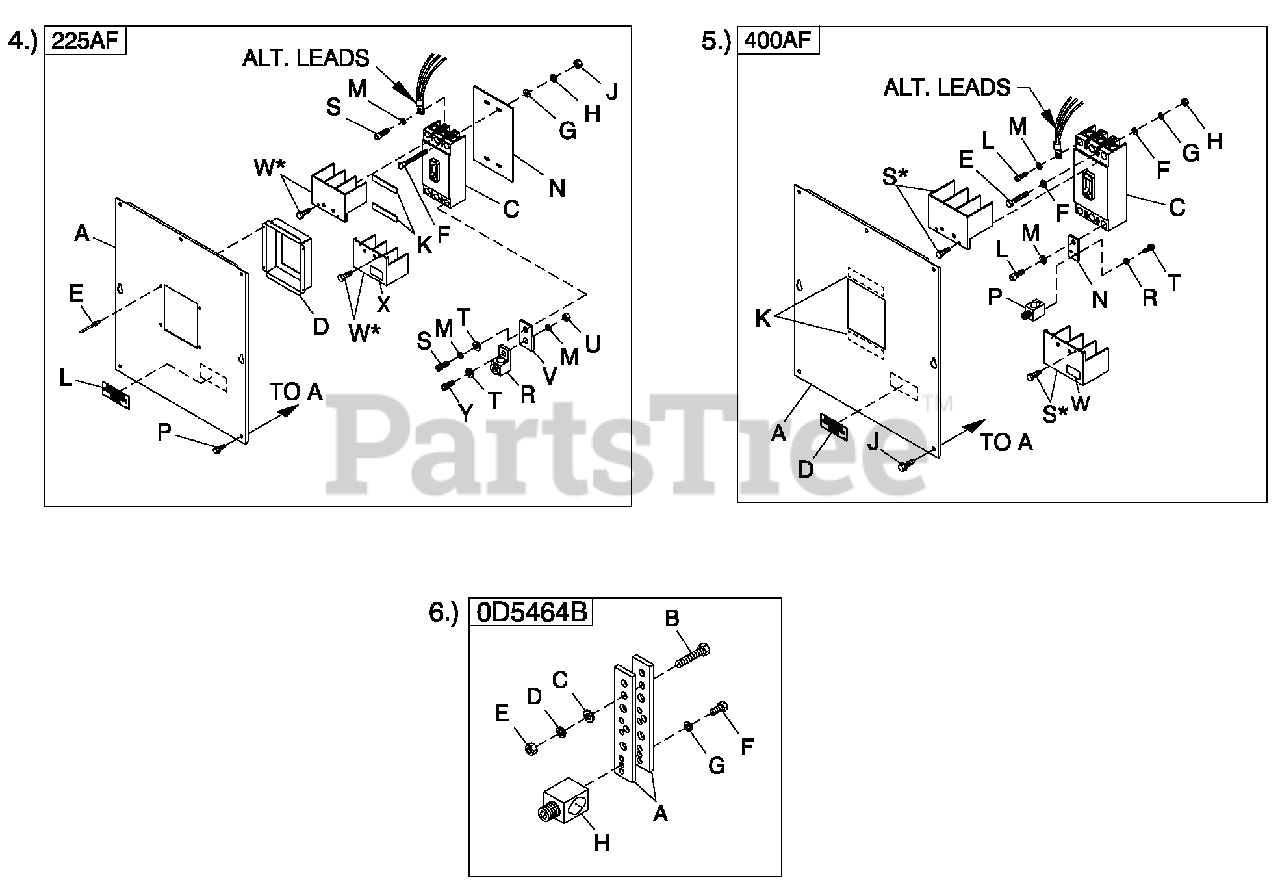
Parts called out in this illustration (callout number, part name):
A	COVER CB C3 225AF
C	CIRCUIT BREAKERS 200A FRAME
D	COVER CB DISH 225AF
E	RIVET POP .125 X .275 SS
F	SCREW RHM #8-32X3-1/4
G	WASHER FLAT #8 ZINC
H	WASHER LOCK #8-M4
J	NUT HEX #8-32 STEEL
K	TAPE ELEC 1/2 FOAM
L	DECAL CUSTOMER CONNECT INSIDE
M	WASHER LOCK M8-5/16
N	INSULATOR CB 225AF
P	SCREW THF M6-1 X 16 N WA Z/JS
R	LUG SLDLSS 300 MCM-6 AL/CU
S	SCREW SHCM8-1.25X 20 G8
T	WASHER FLAT 5/16-M8 ZINC
U	NUT HEXM8-1.25G8 CLEAR ZINC
V	BUS BAR 200A LUG ADAPTOR
W	TERMINAL COVER CB
X	DECAL TERMINAL SHOCK HZD BI
Y	SCREW SHC M8-1.25 X 25 G12.9
A	COVER CB C3 400AF
C	CIRCUIT BREAKERS 400A FRAME
D	DECAL CUSTOMER CONNECT INSIDE
E	SCREW RHM 10-32X4
F	WASHER FLAT #10 ZINC
G	WASHER LOCK #10
H	NUT HEX #10-32 STEEL
J	SCREW THF M6-1 X 16 N WA Z/JS
L	SCREW SHC M10-1.5 X 25 G12.9
M	WASHER LOCK M10
N	BUS BAR CB ADAPTER 225-400 A
P	LUG SLDLSS 600/250-1/0 X 1/4-28
R	WASHER FLAT 3/8-M10 ZINC
S	TERM COVER CB
T	SCREW HHC 1/4-28 X 1/2 G5
U	SCREW SHC M10-1.5 X 25 G12.9
V	WASHER LOCK M10
W	DECAL TERMINAL SHOCK HZD BI
A	BUS BAR NEUTRAL BLOCK 390
B	SCREW HHC M8-1.25 X 45 G8.8 FT
C	WASHER FLAT 5/16-M8 ZINC
D	WASHER LOCK M8-5/16
E	NUT HEXM8-1.25G8YEL CHR
F	SCREW HHC 1/4-28 X 3/4 G5
G	WASHER LOCK M6-1/4
H	LUG SLDLSS 600/250-1/0X1/4-28
